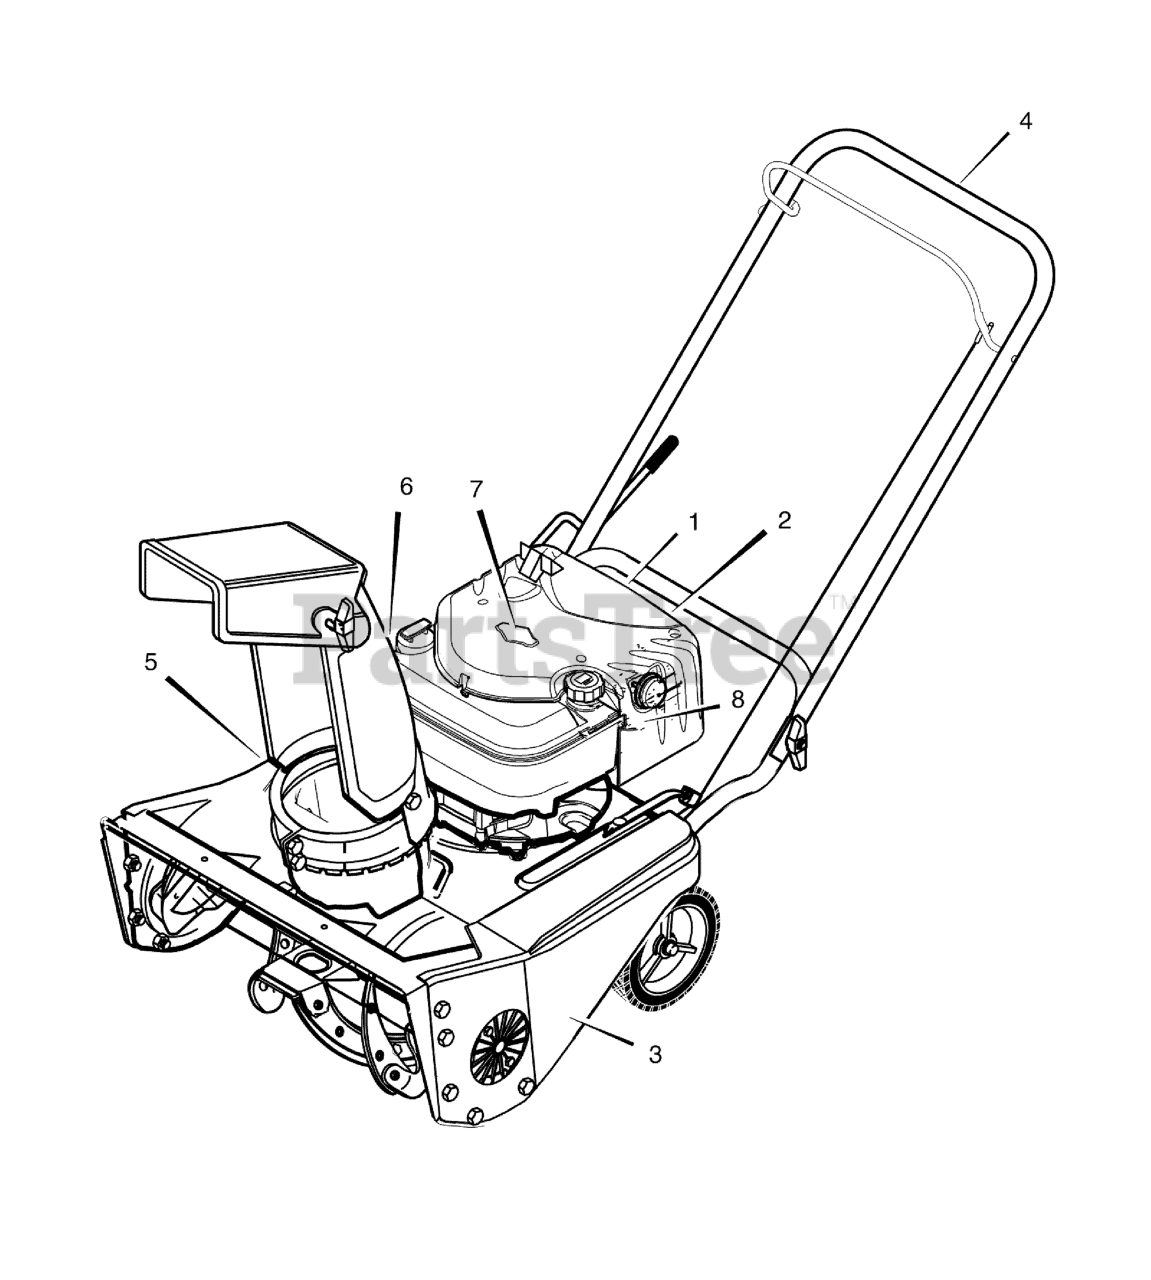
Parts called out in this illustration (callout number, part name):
1	Decal, 4hp / 21"
2	Decal, Choke
3	Decal, Belt Instruction (inside cover)
4	Decal, Auger Control Lever
5	Decal, Danger Auger (Foot)
6	Decal, Danger Chute (Hand)
7	Decal, Briggs & Stratton
8	Decal, Primer Bulb
